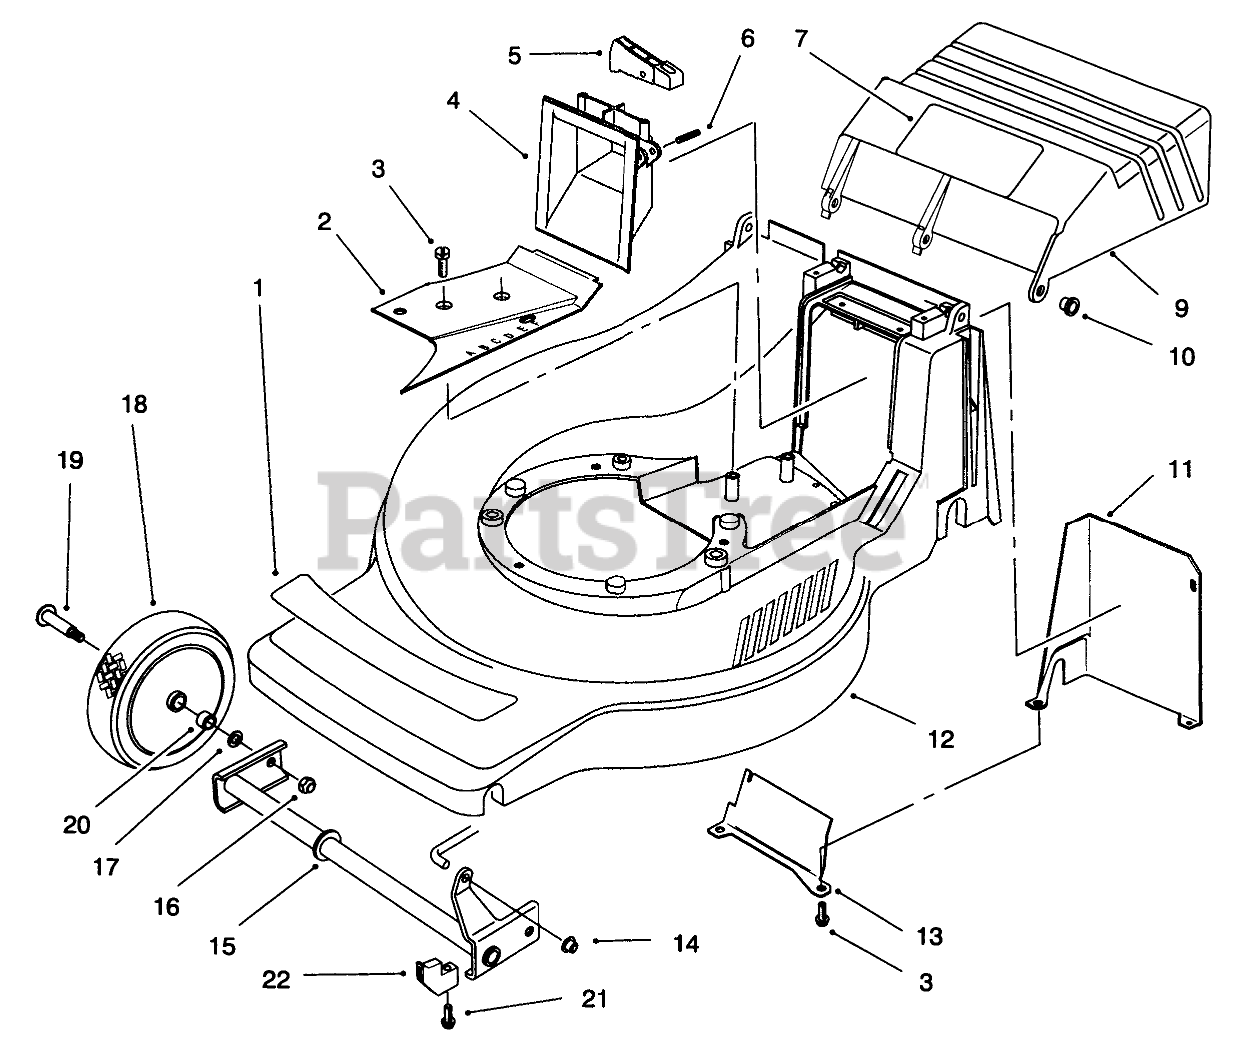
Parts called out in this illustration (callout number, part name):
1	DECAL - DECK
2	COVER - BELT
3	SCREW-RH
4	GRIP - LOWER
5	TRIGGER - HOC
6	PIN-SPIRAL
7	DECAL-DANGER
9	Door-Discharge
10	BUSHING-DOOR
11	COVER - SHIELD
12	HOUSING - 43 CM
13	BAFFLE-BAGGER, REAR
14	NUT-PUSH
15	AXLE-FRONT
16	NUT-LOCK
17	WASHER
18	WHEEL-FRONT
19	WHEEL BOLT
20	BUSHING
21	SCREW-RETAINER
22	RETAINER - AXLE
